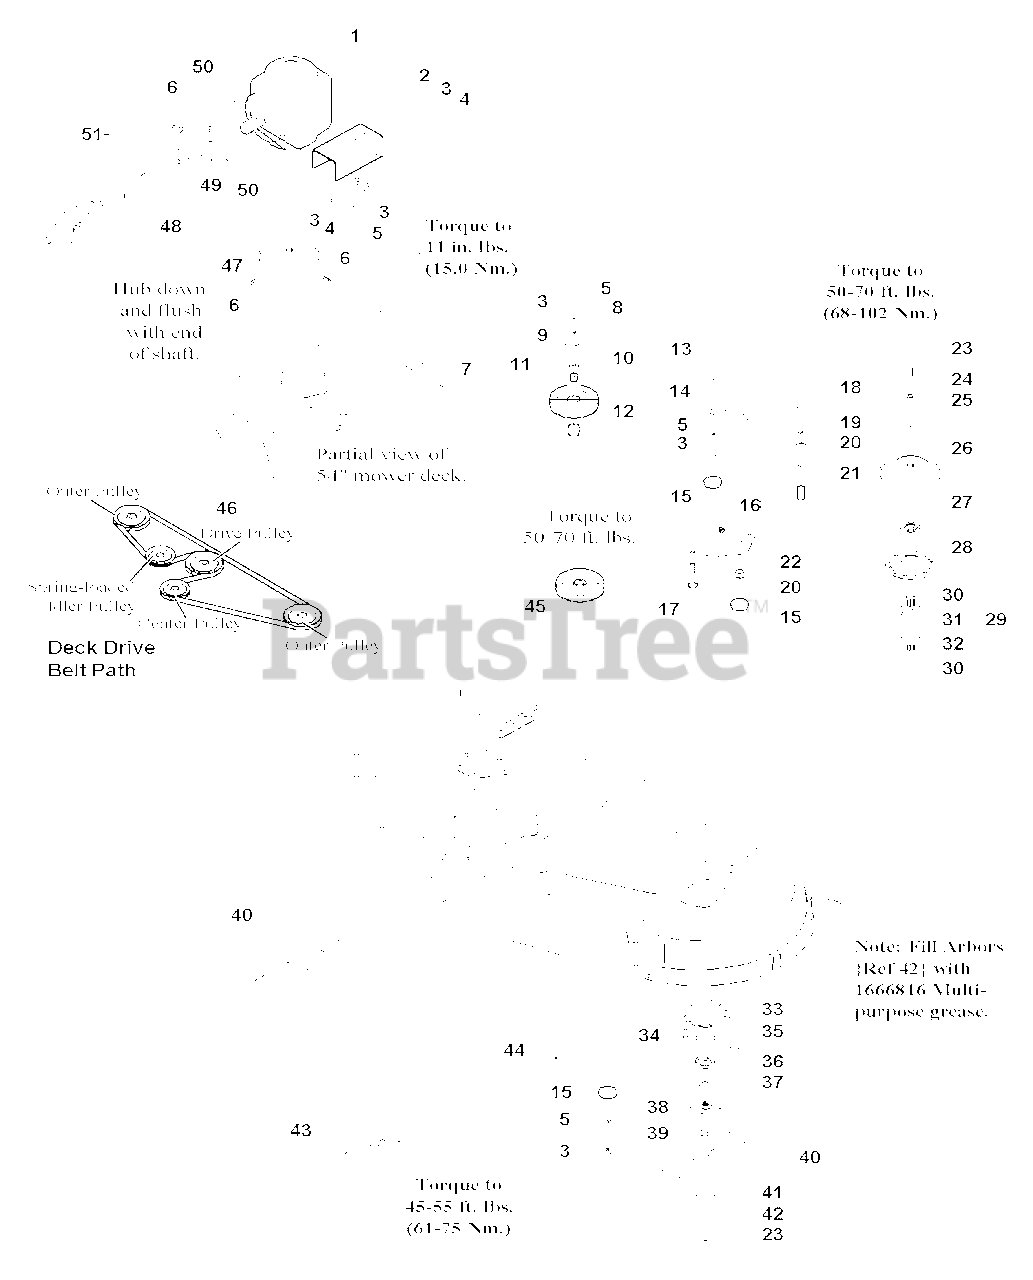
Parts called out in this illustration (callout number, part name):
1	GEAR BOX, 54" Mower Deck (See Gear Box Service Parts )
2	BRACKET, U, 5-1/2 x 2
3	LOCKWASHER, 3/8
4	CAPSCREW, Hex Head, 3/8-16 x 3/4,
5	NUT, 3/8-16
6	SET SCREW, Square Head, 5/16-18 x 1/2, G8
7	CAPSCREW, Hex Head, 3/8-16 x 1
8	STOP, Idler
9	WASHER, Plain, 3/8
11	PULLEY, Idler, Spring-loaded
13	NUT, Hex, Center Lock, 3/8-16
14	SPRING, Extension
15	WASHER
16	FITTING, Lube
17	CARRIAGE BOLT, 3/8-16 x 2
18	CAPSCREW, Hex Head, 3/8-16 x 2-1/4,
19	WASHER, Plain, 3/8
22	ASSEMBLY, Lever & Hub, Idler
23	CAPSCREW, Hex Head, 7/16-14 x 1-1/4, G8
24	LOCKWASHER, 7/16
25	WASHER, 7/16
26	PULLEY, Side Arbor
27	SHIELD, Bearing Upper, Arbor
28	HOUSING, Arbor, Top
29	ARBOR SHAFT & BEARING ASSEMBLY, Complete (Includes Ref. Nos. 30, 31 & 32)
31	GASKET, Foam
32	ARBOR SHAFT
33	ASSEMBLY, Housing, Bottom (Includes Ref. No. 35)
34	CAPSCREW, Hex Head, Taptite, 5/16-18 x 3/4
35	FITTING, Lube
36	SHIELD, Grass
37	WASHER, Shim
38	ADAPTER, Blade
39	RING, Self Locking
40	BLADE, Mower, 20-1/2 (S/N 1-59999)
40	BLADE, Mower, 20-1/2 (S/N 60000 and above)
41	WASHER, Spline
42	WASHER, Spring
43	BLADE, Mower, 16 (S/N 1-59999)
43	BLADE, Mower, 16 (S/N 60000 and above)
44	CAPSCREW, Hex Head, 3/8-16 x 1-1/2
45	PULLEY, Center Arbor
47	PULLEY, Gear Box
48	DRIVE SHAFT, Complete (See Drive Shaft Service Parts )
49	CAPSCREW, Hex Head, 1/4-20 x 2-1/4
51	NUT, Hex, Center Lock, 1/4-20
